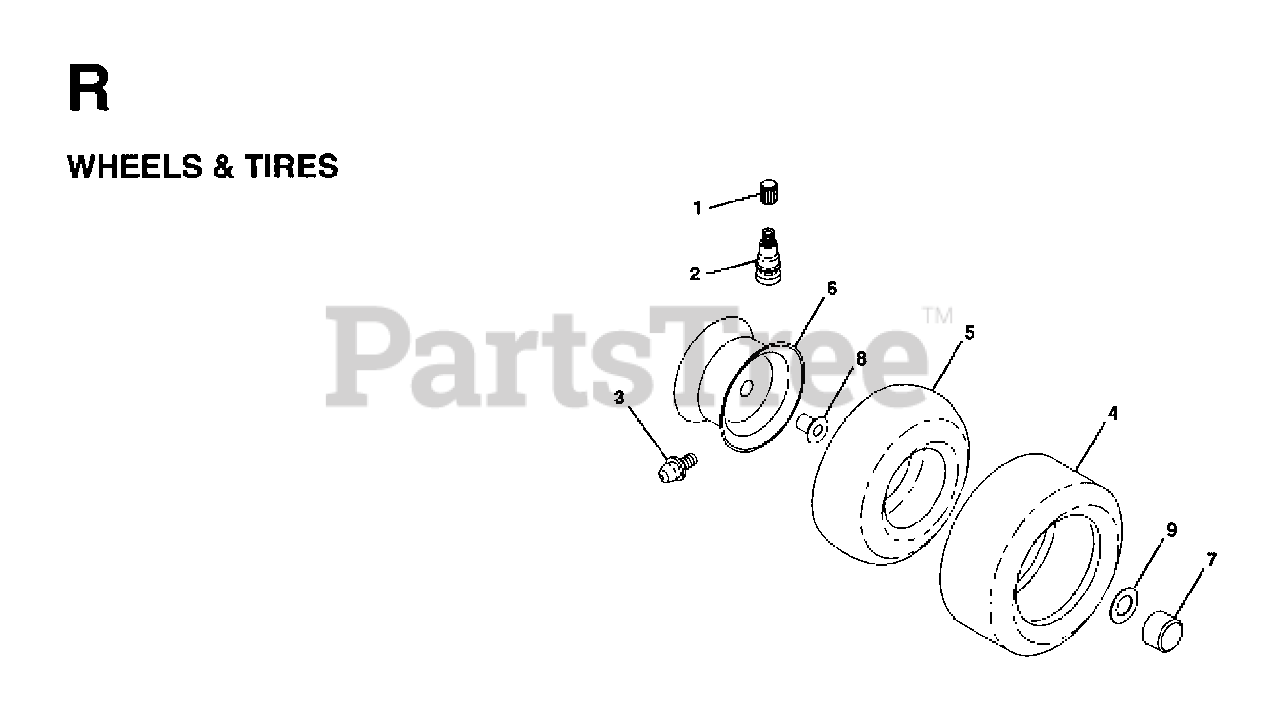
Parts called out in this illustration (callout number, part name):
1	VALVE CAP
2	VALVE STEM LT
3	FITTING LT
4	TIRE.TS 13X5-6
4	TIRE HEAVY DUTY
5	TUBE.5.3/4.5/6
5	TUBE.16X6.5/7.5-8
6	RIM
6	RIM REAR 8"
7	CAP-HUB FRONT LT
8	BEARING T
